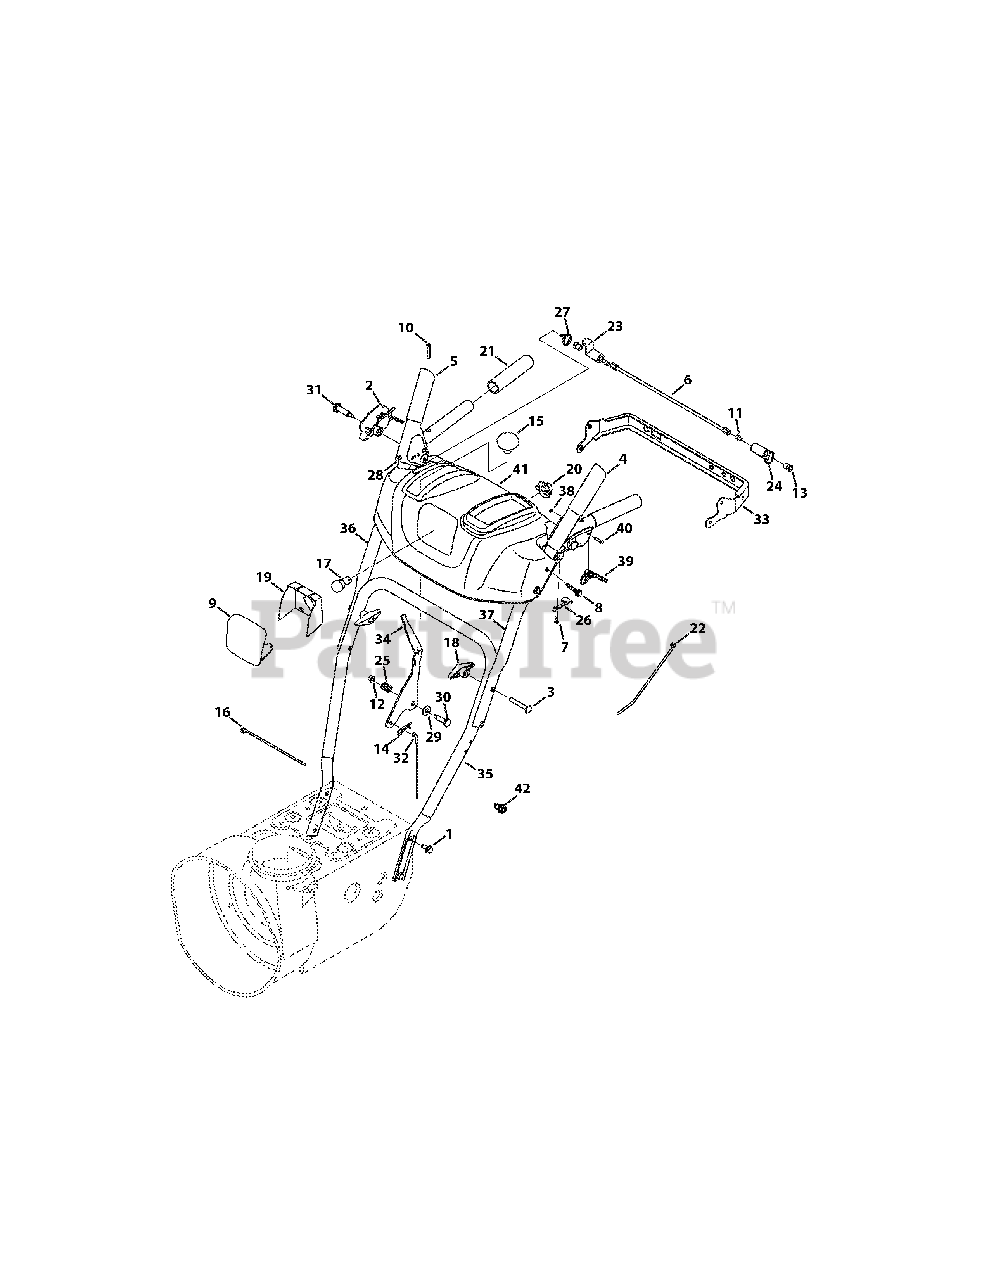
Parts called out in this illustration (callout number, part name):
1	Screw, Taptite, 5/16-18 x .750
2	Clutch Lock, RH
2	Clutch Lock, LH
3	Screw, Carriage, 5/16-18 x 2.50
4	Auger Engage, Black, LH
5	Drive Engage, Black, RH
6	Pivot Rod
7	Screw, Plastite, 8-16 x .50
8	Screw, Taptite, 1/4-20 x 1.625
9	Lens Panel
10	Screw, 10-24 x 1.375
11	Screw, 1/4-20 x .50
12	Nut, Flangelock, 1/4-20
13	Nut, Hex, 1/4-20
14	Click Pin, .092 x 1.64
15	Shift Knob
16	Cable Tie, 7"
18	Wing Knob, 5/16-18
19	Lens Label
20	Lamp Socket
21	Grip, 1.0 ID x 5.0 LG
22	Cable Tie, Push Mount
23	Plate, Lock
24	Cam, Clutch Lock
25	Compression Spring, .39 x .60 x .88
26	Clutch Lock Spring
27	Torsion Spring, 0.8156 x .3038
28	Rubber Bumper
29	Washer, Flat, .385 x .87
30	Screw, Shield, .374 x 1.05
31	Screw, Shoulder, .437 x 1.345 x 1/4-20
32	Speed Selector Cable
34	Shift Lever
35	Lower Handle
36	Upper RH Handle
37	Upper LH Handle
38	E-Ring
39	Steering Trigger Control
40	Steering Trigger Pin, 3/16
41	Handle Panel Black
42	Screw, TT, 1/4-20 x .500 (For ground wire)
